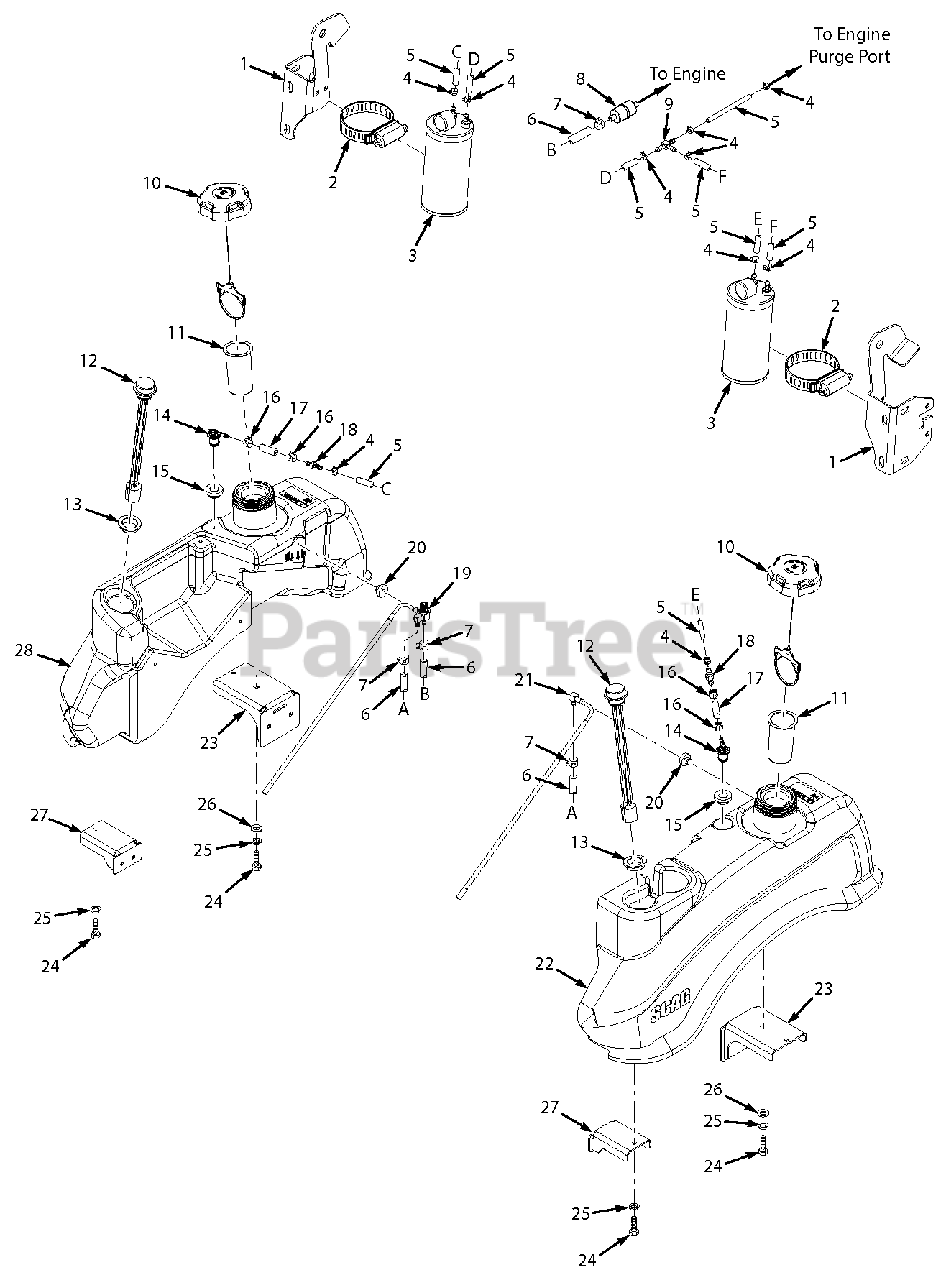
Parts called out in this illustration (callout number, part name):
1	ROPS Mount, LH
1	ROPS Mount, LH, 29CV-EFI
1	ROPS Mount, RH
1	ROPS Mount, RH, 29CV-EFI
3	Carbon Canister, 400cc
3	Dust Filter, Carbon Canister
4	Clamp, Vapor Recovery Hose
5	Hose, 3/16" (order by inch)
6	Hose, Non-Perm Fuel 1/4" I.D.
7	Clamp, Fuel Hose 1/4" I.D.
8	Fuel Filter
9	Tee, 3/16 x 3/16 x 3/16 Union, Hose Barb
10	Fuel Cap, Tethered
10	Fuel Cap, Tethered (California Only)
11	Tube, Fuel Tank Insert - 4"
12	Fuel Gauge Assembly
13	Seal, Fuel Gauge
14	Remote Vent
15	Grommet, Viton
16	Clamp, Fuel Hose 7/32
17	Hose, Vapor Recovery (order by inch)
18	Mender, 1/4 x 3/16
19	Fuel Tube Assembly, Includes Valve
20	Bushing, .56 Viton
21	Fuel Tube Assembly, LH
22	Fuel Tank Assembly, LH
23	Mounting Bracket, Fuel Tank Rear
24	Bolt, Hex Head 5/16-18 x 3/4"
25	Lockwasher, 5/16" Spring
26	Flatwasher, 5/16-.375 x .875 x .083
27	Mounting Bracket, Fuel Tank Front
28	Fuel Tank Assembly, RH
